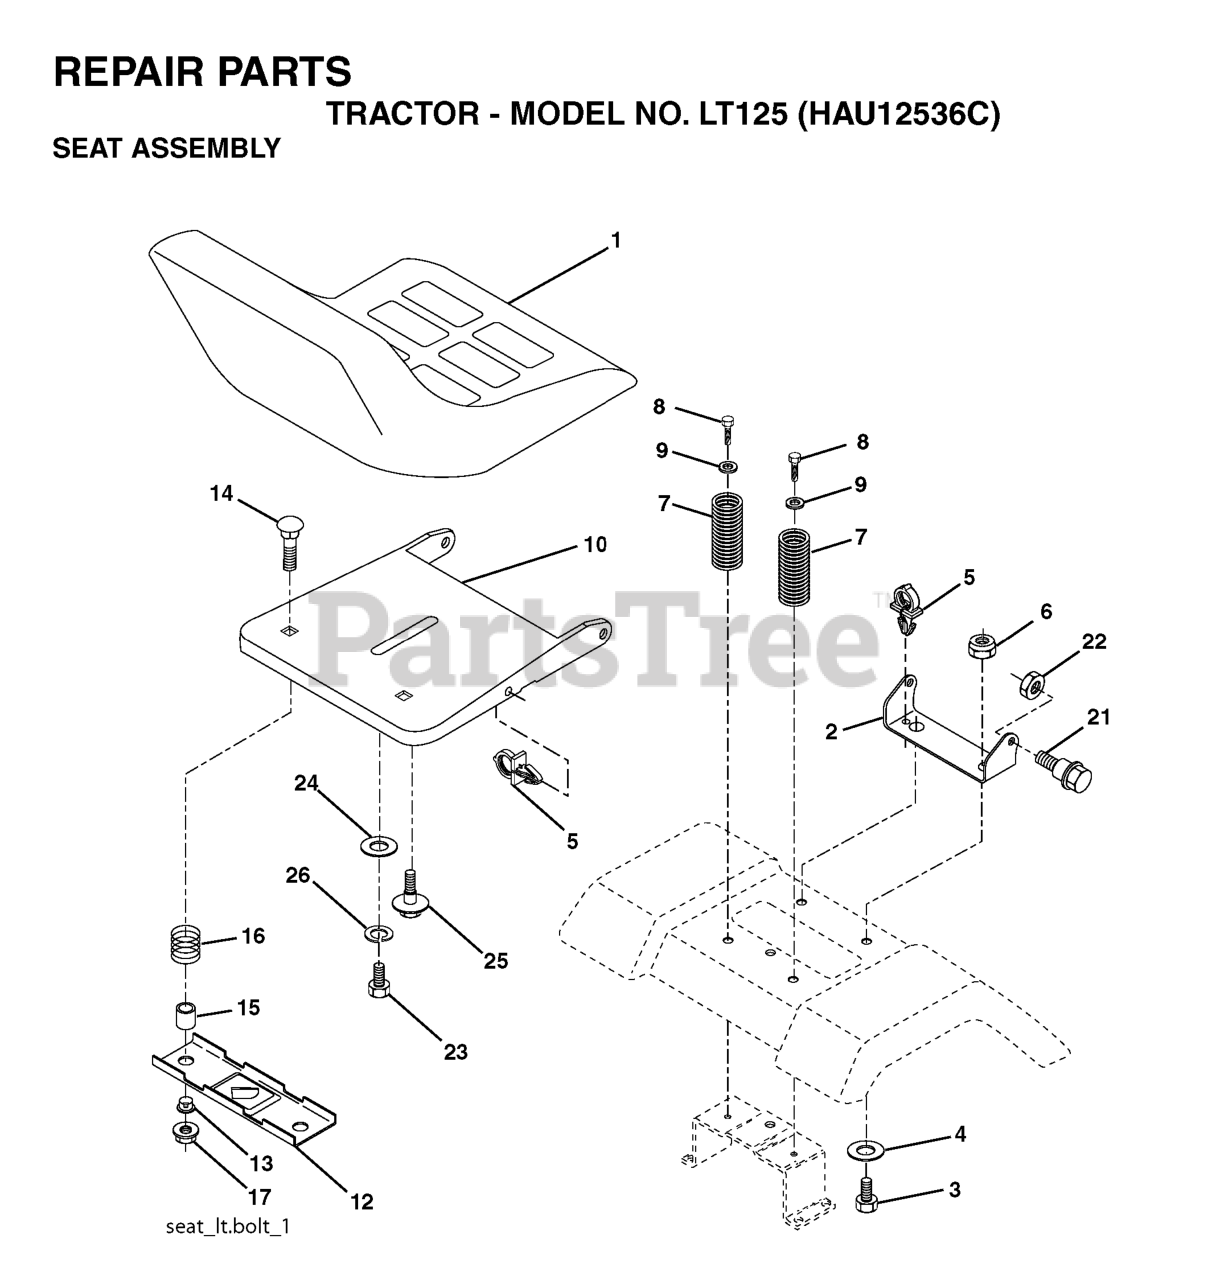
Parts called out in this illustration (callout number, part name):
1	SEAT
2	SEAT PIVOT BRKT
3	BOLT, HEX 3/8-16X1
6	NUT
7	SPRING COMPRESSION
8	SCREW 3/8-16X1
9	WASHER
10	PAN SEAT
12	BRKT SWITCH
14	BOLT.ROUND.HEAD.SQUARE.NECK
15	SPACER SPLIT 28X.96
17	NUT T
21	BOLT.SHOULDER.5/16-18
22	NUT.71038.31-18.HEX.NYLOCK
23	BOLT.HEX.BLACK
25	BOLT,SHOULD
26	LOCKWASHER
